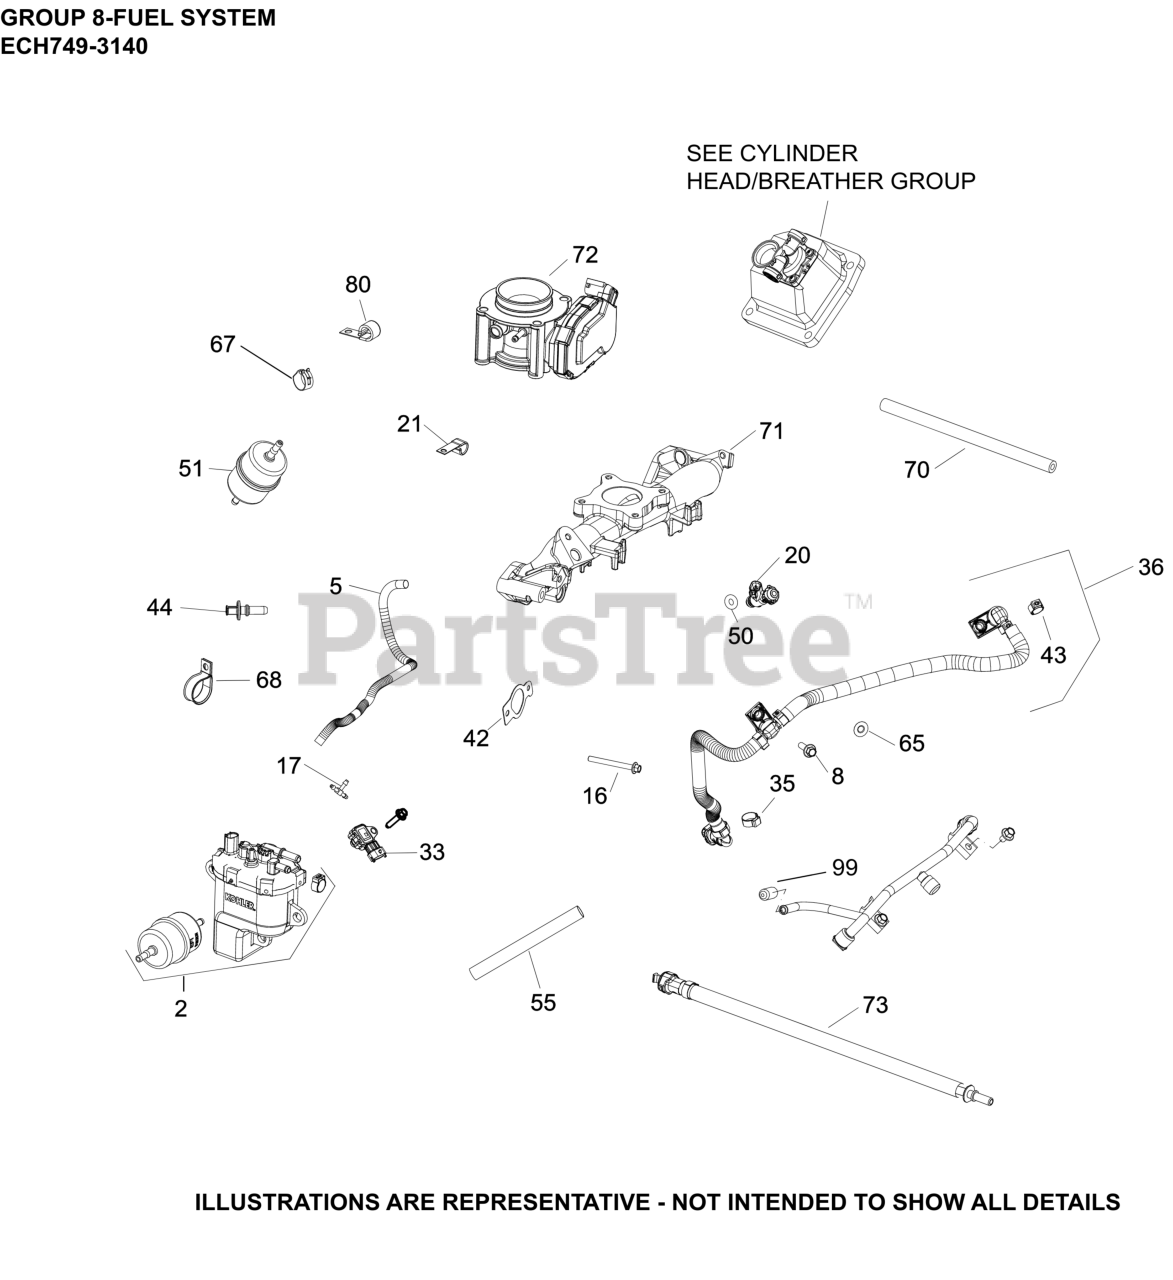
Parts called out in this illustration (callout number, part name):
2	KIT, FUEL PUMP MODULE
5	SLEEVE, ANTI-ABRASION
8	SCREW, FLG M6x1.0x20
16	SCREW, FLG M6X1.0X60
17	TEE CONNECTOR
20	INJECTOR, FUEL
21	CLIP, CABLE
33	SENSOR, T-MAP
35	CLAMP, HOSE
36	FUEL HOSE ASSEMBLY,ECH680-ECH749
42	KIT, INTAKE MANIFOLD GASKET
43	CLAMP, OETIKER
44	PLUG, FITTING FUEL
50	KIT, FUEL INJECTOR O-RING
51	FILTER, FUEL
55	SLEEVE, ANTI ABRASION -USE 25 431 12-S
55	SLEEVE, ANTI ABRASION-USE 25 431 12-S
65	CLIP, RETAINER
67	CLAMP, SPRING HOSE
68	CLAMP, INSULATED
70	HOSE, FUEL LOW-PERMEATION
71	MANIFOLD, INTAKE - ETB HORIZONTAL
72	BODY, ELECTRONIC THROTTLE ASM 30 DIA
73	HOSE, FPM EXTENSION 25 111 201-S
80	CLIP, CABLE (KM)
99	CAP, MASKING
NI	FITTING, FUEL - STRAIGHT
NI	HOSE, EVAPORATIVE 20"- (#24326143S)
NI	SLEEVE, ANTI ABRASION
